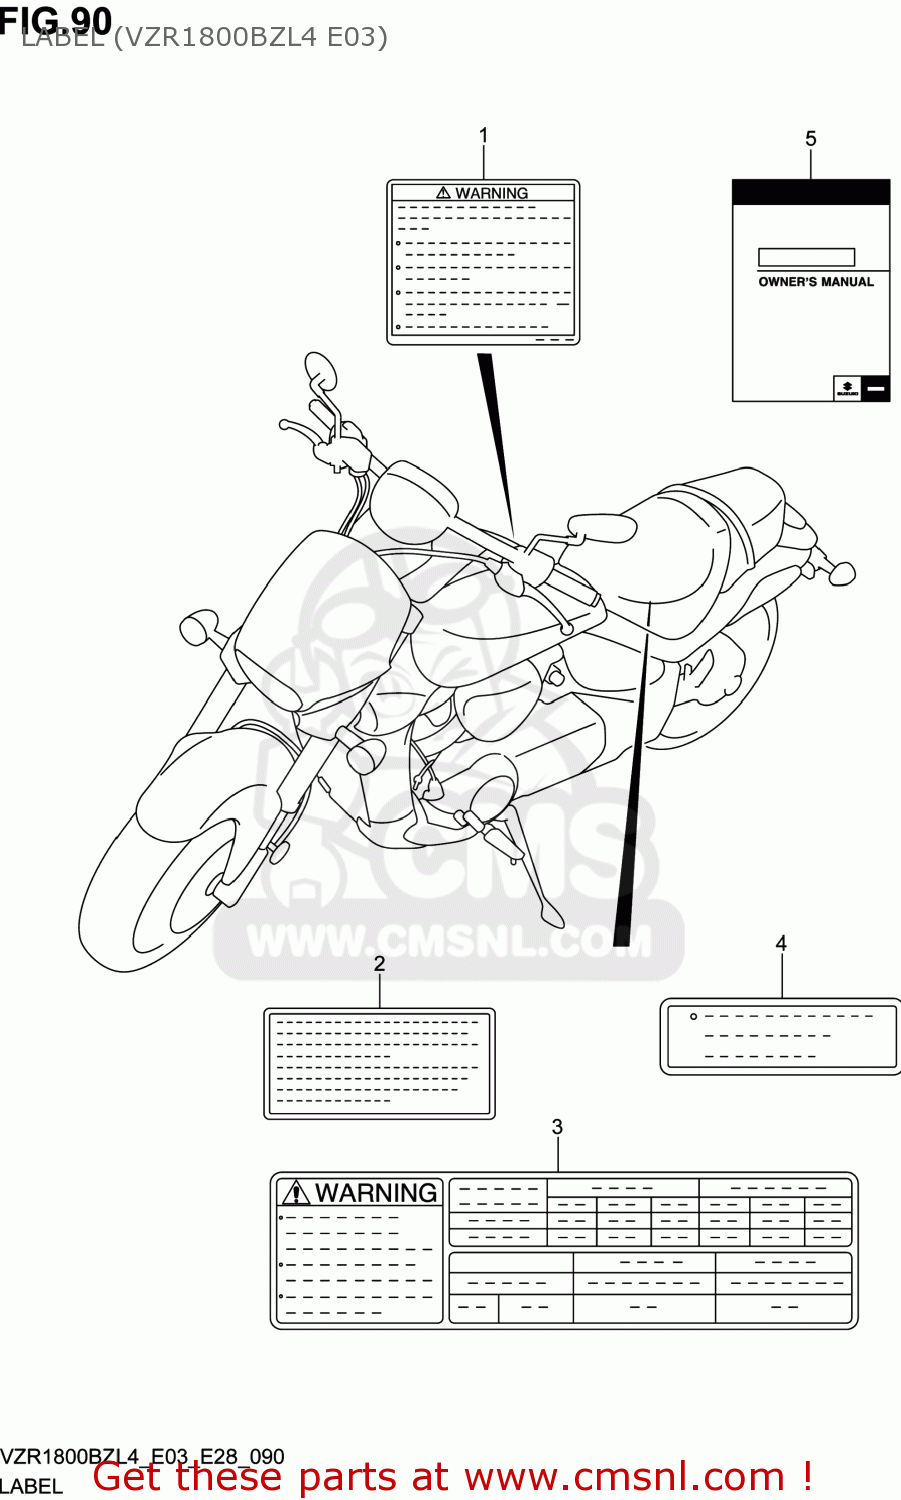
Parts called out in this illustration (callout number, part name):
1	LABEL,GENERAL WARNING
2	LABEL,MANUAL NOTICE
3	LABEL,TIRE INFORMATION
4	LABEL,FUEL INFORMATION
5	MANUAL,OWNER'S
